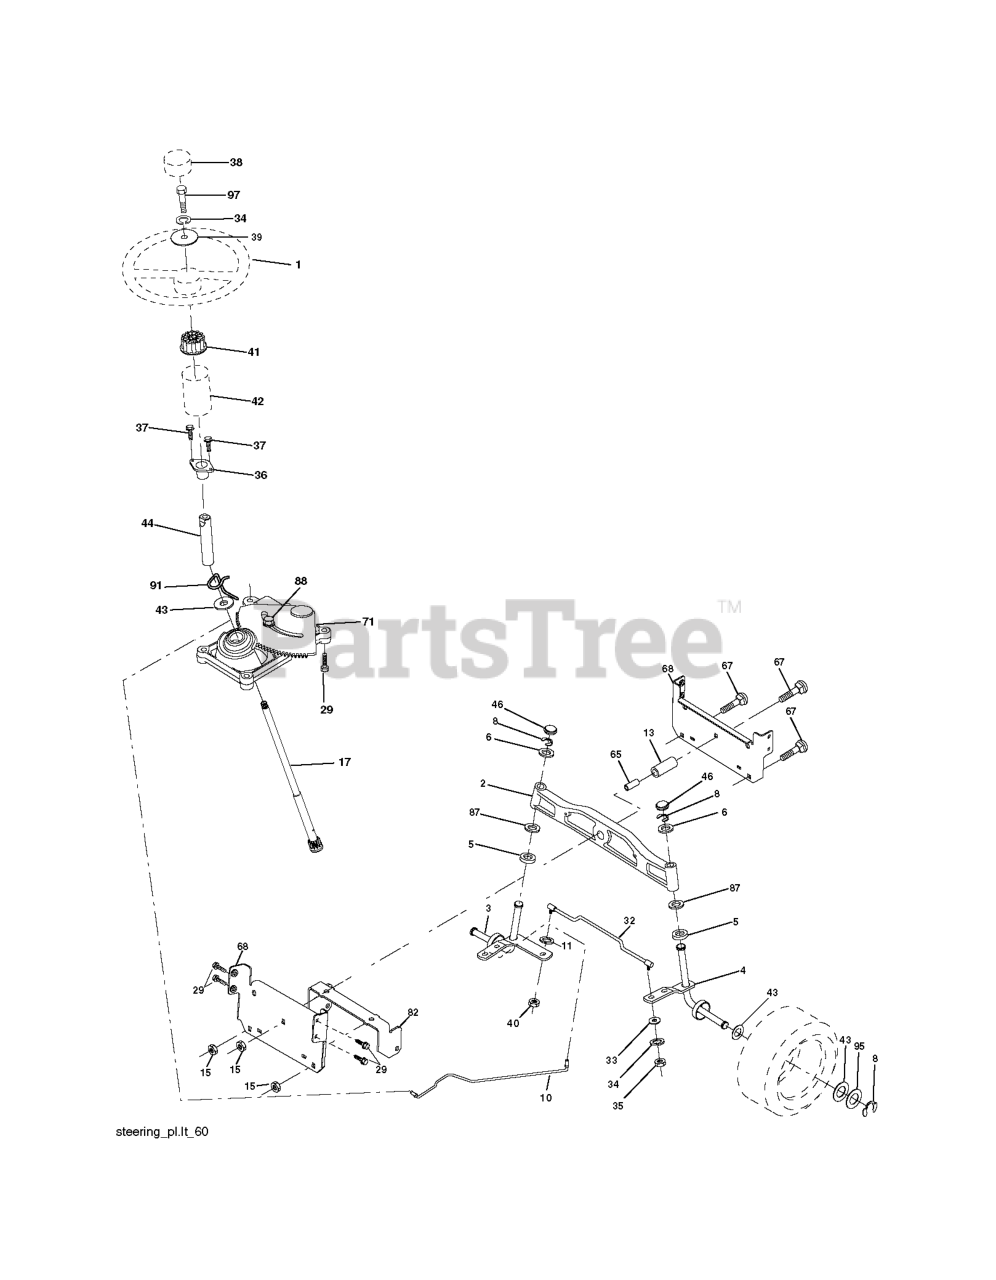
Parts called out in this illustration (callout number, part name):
1	STEERING WHEEL
2	AXLE ASSY FRONT
3	SPINDLE.ASM.LH.15"TIRES
4	SPINDLE.ASM.RH.15"TIRES
5	THRUST WASHER
10	DRAGLINK.15".TIRES.2001
11	WASHER, LOCK 3/8
13	TUBE, PIVOT AXLE
15	NUT
17	SHAFT STEERING SPLINE
29	SCREW, 3/8-16X3/4
33	WASHER M
34	WASHER.LOCK.HVY.HLCL.SPR.5/16
35	NUT, CROWNLOCK
36	BUSHING, STEERING
37	SCREW.TT.#10-32X.5.3/8.FLANGE
38	INSERT.CAP.STRG.WH.GRAY
39	WASHER.11/32
40	NUT CROWNLOCK 3/8-24
41	ADAPTER, WHEEL STNG..
42	BOOT, STEERING
44	SHAFT.EXTEN.STRG.SPLINE
46	CAP.SPINDLE.BLACK
65	SPACER BRACE AXLE
67	BOLT CARRIAGE
68	BRACE.AXLE.15"TIRES
71	STEERING ASM
82	BRACKET.SUSP.CHASSIS.FRONT.15
87	WASHER, FLAT .781 X 1 1/2"
88	BOLT, SHOULDER 7/16-20
91	CLIP.STEERING
95	WASHER.HARDENED
